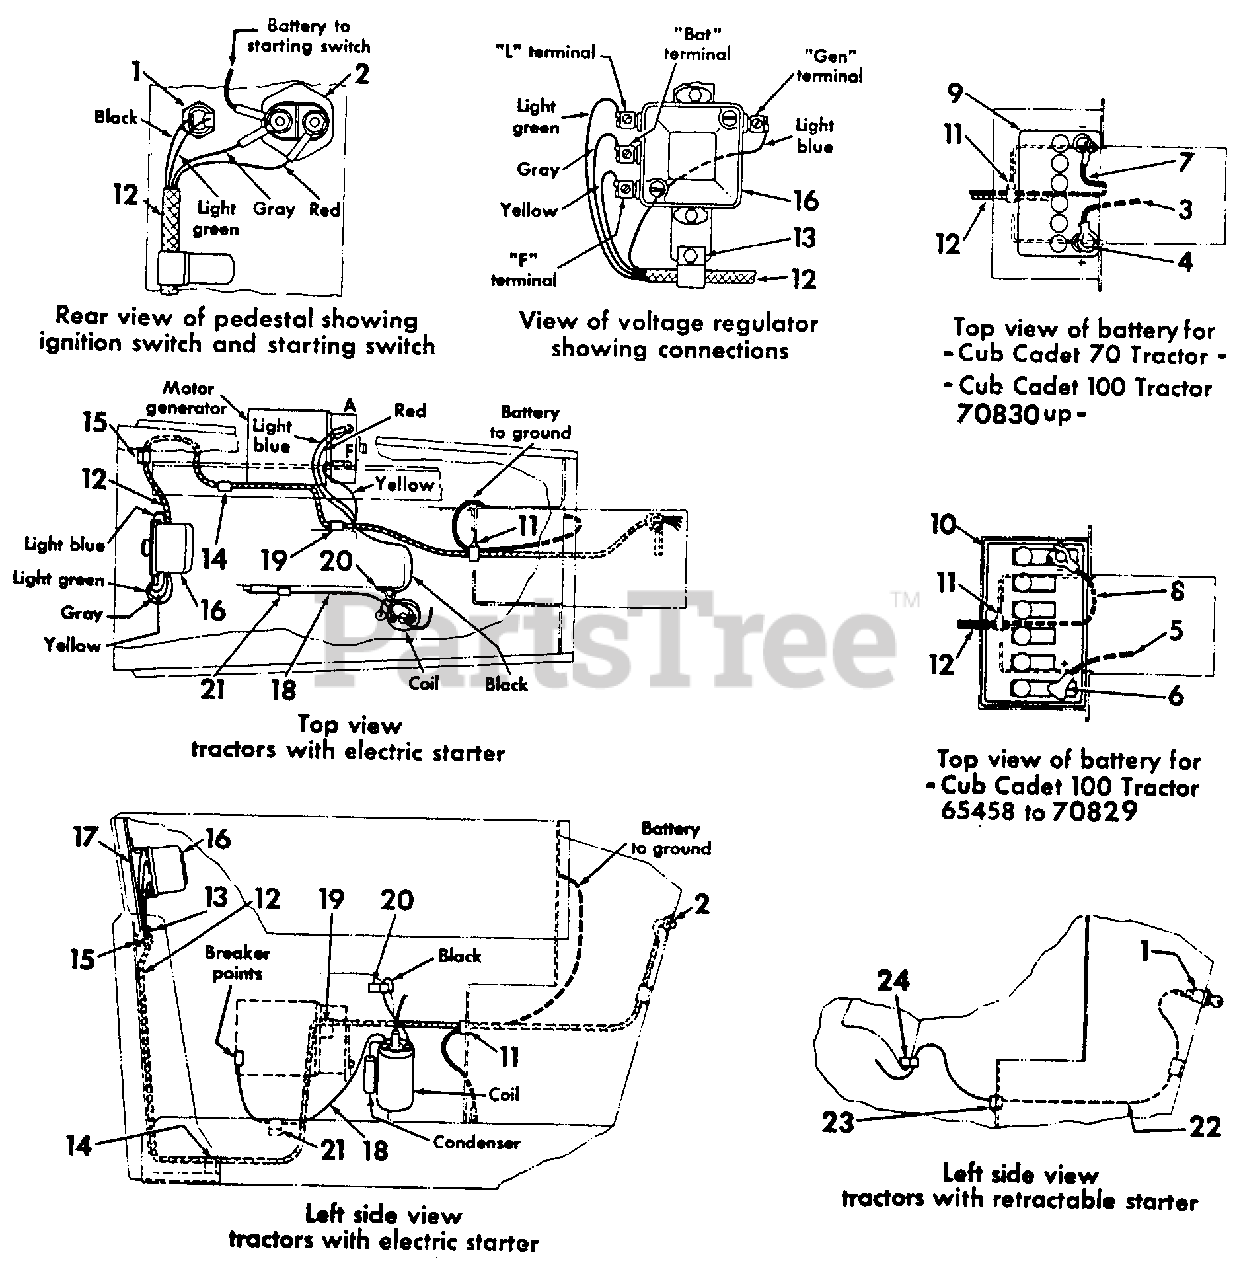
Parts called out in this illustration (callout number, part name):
1	Switch Assy, Ignition (Unit A)
2	Switch Assy, Starting (Unit A)
3	Cable Assy, Battery to Starting Switch (Unit A)
4	Cover, Battery Terminal (Unit A)
5	Cable w/Bolt and Cover, Battery to Starting Switch (Unit A)
6	Cover, Battery Terminal (Unit A)
7	Cable Assy, Battery to Ground (Unit A)
8	Cable w/Bolt Assy, Battery to Ground (Unit A)
9	Battery, Prestolite 9948X, 12 Volt
10	Battery, Prestolite 2481X, 12 Volt
11	Clip, Cable Harness (Unit A)
12	Harness Assy, Cable (Unit A)
13	Clip, Cable Harness (Unit A)
14	Clip, Cable Harness (Unit A)
15	Clip, Cable Harness (Unit A)
16	Regulator Assy, Voltage (Unit A)
17	Strap, Voltage Regulator Mounting (Unit A) Screw
18	Cable, Ignition Coil Negative Terminal to Braker Points
19	Clip, Cable Harness
20	Clip, Cable
21	Clip, Cable
22	Cable, Ignition Switch to Magneto (Unit B)
23	Clip, Cable (Unit B)
24	Clip, Cable
